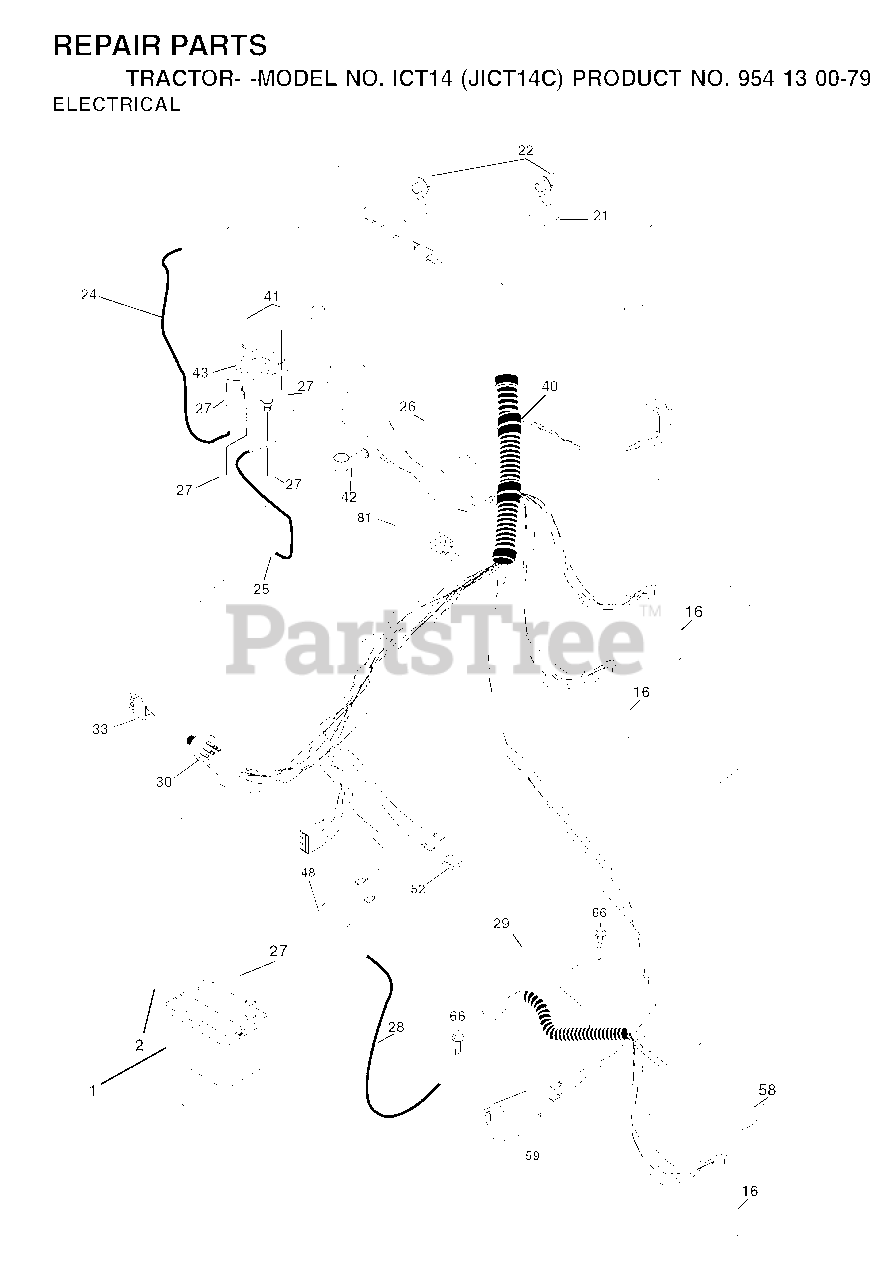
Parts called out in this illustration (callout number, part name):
1	REPL BY 532 12 38-99
16	SWITCH INTERLOOK PUSH-IN
21	HARNESS.W/LIGHT SOCKET
22	LIGHTBULB
24	BATTERY CABLE GT
25	CABLE BATTERY
26	FUSE 20AMP
27	NUT
28	CABLE GROUND
29	PLUNGER SWITCH (COLOR:OLIVE)
30	IGNITION SWITCH
33	KEY MLD GEN DELTA
42	TERMINAL COVER
43	SOLENOID
52	WIRE PROTECTION LOOP
58	BUZZER
66	SCREW LT
81	RELAY.ASSY.T
